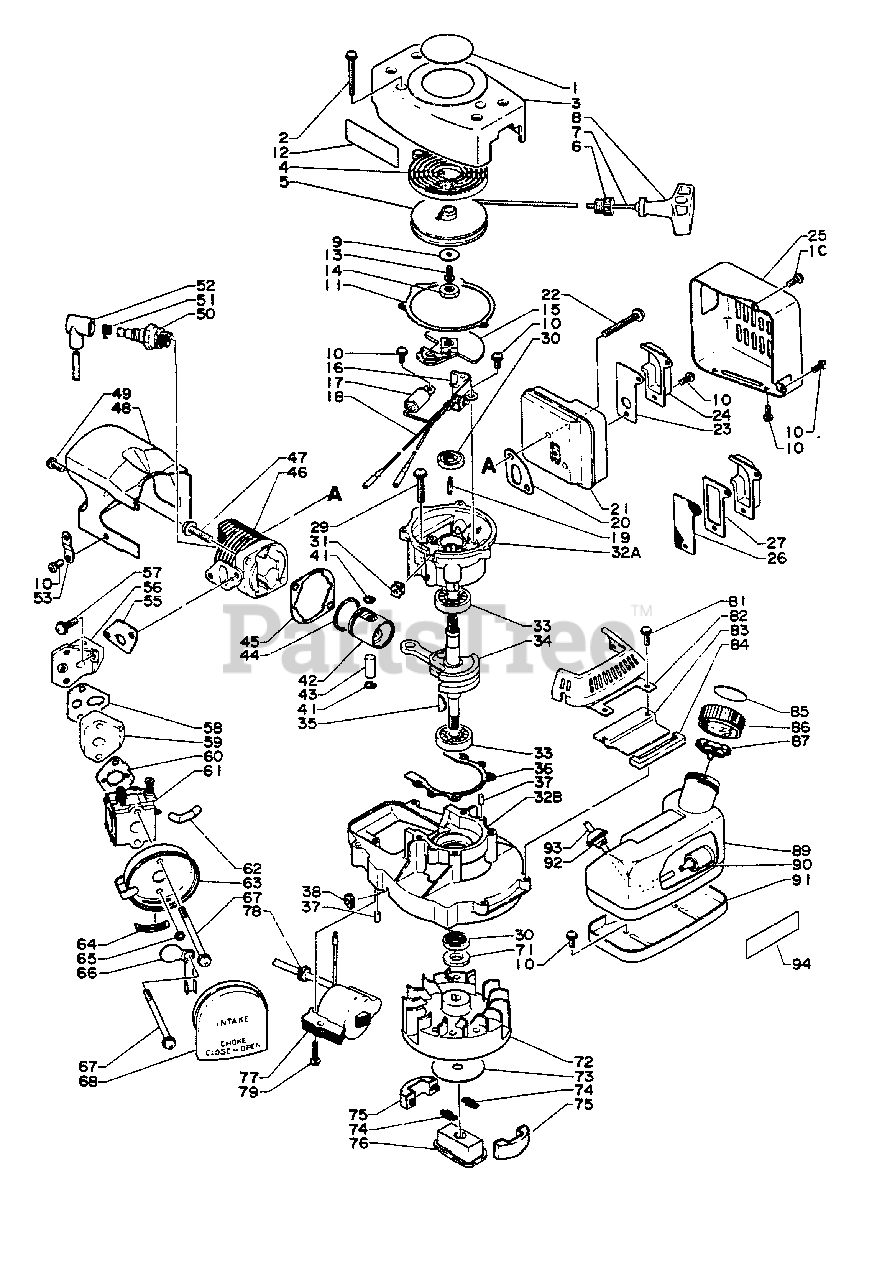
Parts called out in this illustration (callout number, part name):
1	LABEL - ECHO
2	SCREW 4×40
3	CASE, STARTER
4	SPRING, RECOIL
5	REEL, ROPE
6	GUIDE, ROPE
7	ROPE, STARTER 3.0×850
8	GRIP, STARTER
9	WASHER 4.1×15.5×1T
10	SCREW 4×10
11	GASKET, STARTER
12	LABEL - CAUTION
13	SCREW - 4×10
14	NUT 8×1.25
15	PAWL ASSY, STARTER
16	CONTACT POINT SET
17	CONDENSER
18	LEAD - GROUND
19	PAD, OIL
20	GASKET, EXHAUST
21	CASE, MUFFLER
22	SCREW 5×40
23	GUIDE, EXHAUST - INNER
24	COVER, MUFFLER
25	COVER, MUFFLER
26	SCREEN, SPARK ARRESTER
27	RETAINER, SCREEN
29	SCREW 5×30
30	SEAL, OIL
31	GROMMET, LEAD
32	CRANKCASE KIT
33	BEARING, BALL 6200
34	CRANKSHAFT
36	GASKET, CRANKCASE
37	PIN, LOCATING 4
41	RING, SNAP
42	PISTON
43	PIN, PISTON
44	RING, PISTON
45	GASKET, CYLINDER
46	CYLINDER
47	SCREW 6×20
48	COVER, CYLINDER
49	SCREW 5×10
50	SPARK PLUG - BM6A
50	SPARK PLUG - BMR6A
51	TERMINAL, SPARK PLUG CAP
52	CAP, SPARK PLUG
53	BRACKET
55	GASKET, INTAKE
56	BASE, INSULATOR
57	SCREW 5×16
58	GASKET, INTAKE
59	INSULATOR
60	GASKET, INTAKE
61	CARBURETOR - WA
62	TUBE
63	CASE, AIR FILTER
65	WASHER 5.2×8×0.8T
66	SHUTTER, CHOKE
67	SCREW 5×57
68	FILTER, AIR
72	FLYWHEEL
73	PLATE, CLUTCH
74	SPRING, CLUTCH
75	SHOE, CLUTCH
76	BOSS, CLUTCH
77	COIL, IGNITION
79	SCREW 4×20
81	SCREW 4×12
83	BRACKET, FUEL TANK
84	CUSHION, FUEL TANK
85	LABEL - FUEL MIX
86	CAP ASSY
87	VALVE, CHECK
89	BRACKET
90	FILTER, FUEL
93	PIPE, FUEL
